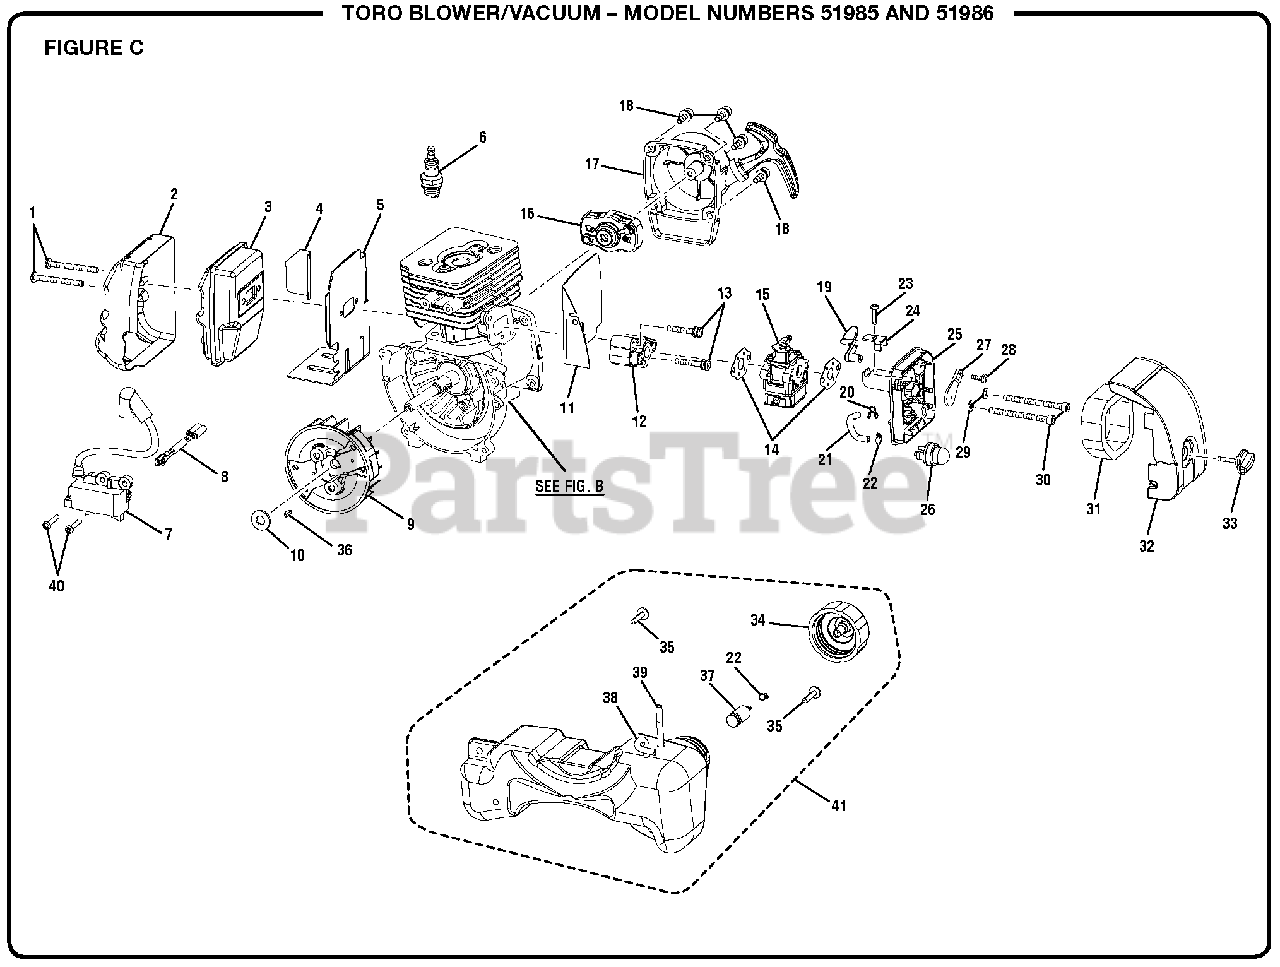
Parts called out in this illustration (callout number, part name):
1	Screw (M5 x 50 mm)
2	Heat Shield
3	Muffler Assembly
4	Heat Shield Tape
5	Muffler Gasket
6	Spark Plug (Champion RC6Y)
7	Ignition Coil Assembly
8	Ignition Lead Assembly
11	Heat Dam Gasket
13	Screw w/Washer (M5 x 31 mm)
14	Carburetor Gasket
15	Carburetor Assembly
16	Pulley Assembly
17	Recoil Starter Assembly
18	Screw w/Washer (M5 x 16 mm)
19	Choke Lever
20	Hose Clip
21	Hose (51mm)
22	Hose Clip
23	Screw (M4 x 16 mm)
24	Retaining Clip
25	Air Box Case
26	Primer Bulb Assembly
27	Choke Plate
28	Screw (M4 x 12 mm)
30	Bolt (M5 x 60 mm)
31	Air Filter
32	Air Box Cover
33	Knob
34	Fuel Cap Assembly
35	Screw (10-14 x 7/8 in.)
36	Woodruff Key
37	Fuel Filter
38	Rubber Tubing (114 mm)
39	Rubber Tubing (214 mm, Low Permeation)
40	Screw (M4 x 22 mm)
41	Fuel Tank and Cap Assembly
